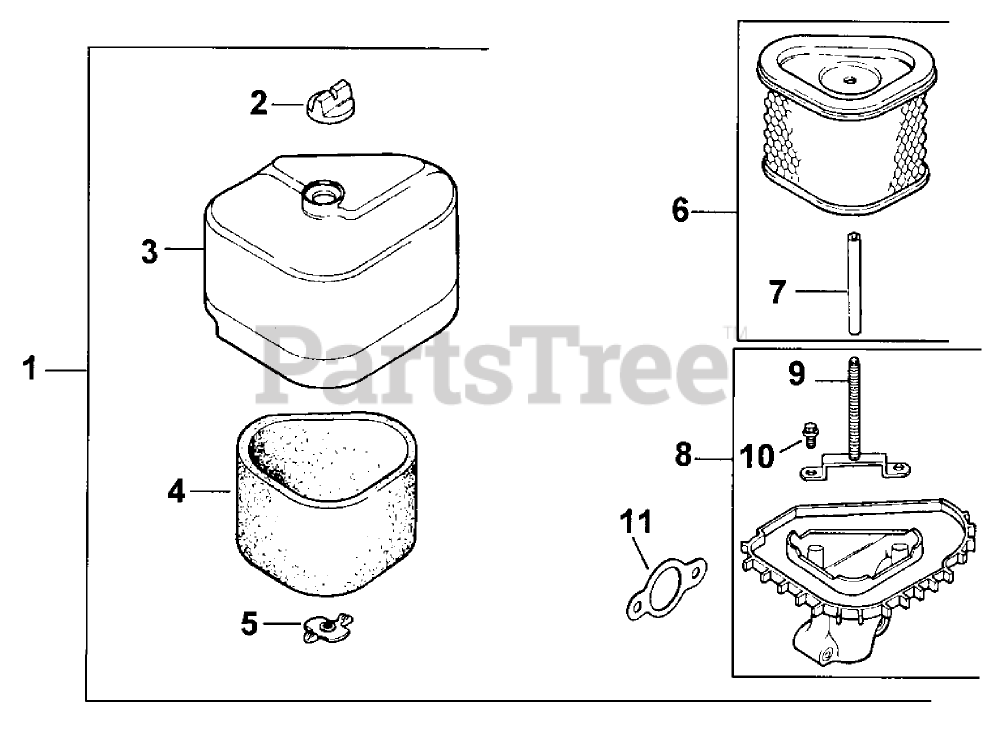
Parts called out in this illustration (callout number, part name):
1	Kit-Air Cleaner (Incl. Ref.# 2-11)
2	Knob-Cover
3	Cover-Air Cleaner
4	Precleaner-Element
5	Wingnut
6	Element-Air Cleaner (Incl. Ref.#7)
7	Seal
8	Base-Air Cleaner (Incl. Ref.#9, 10)
9	Stud-Mounting Plate
10	Screw
11	Gasket-Air Cleaner
